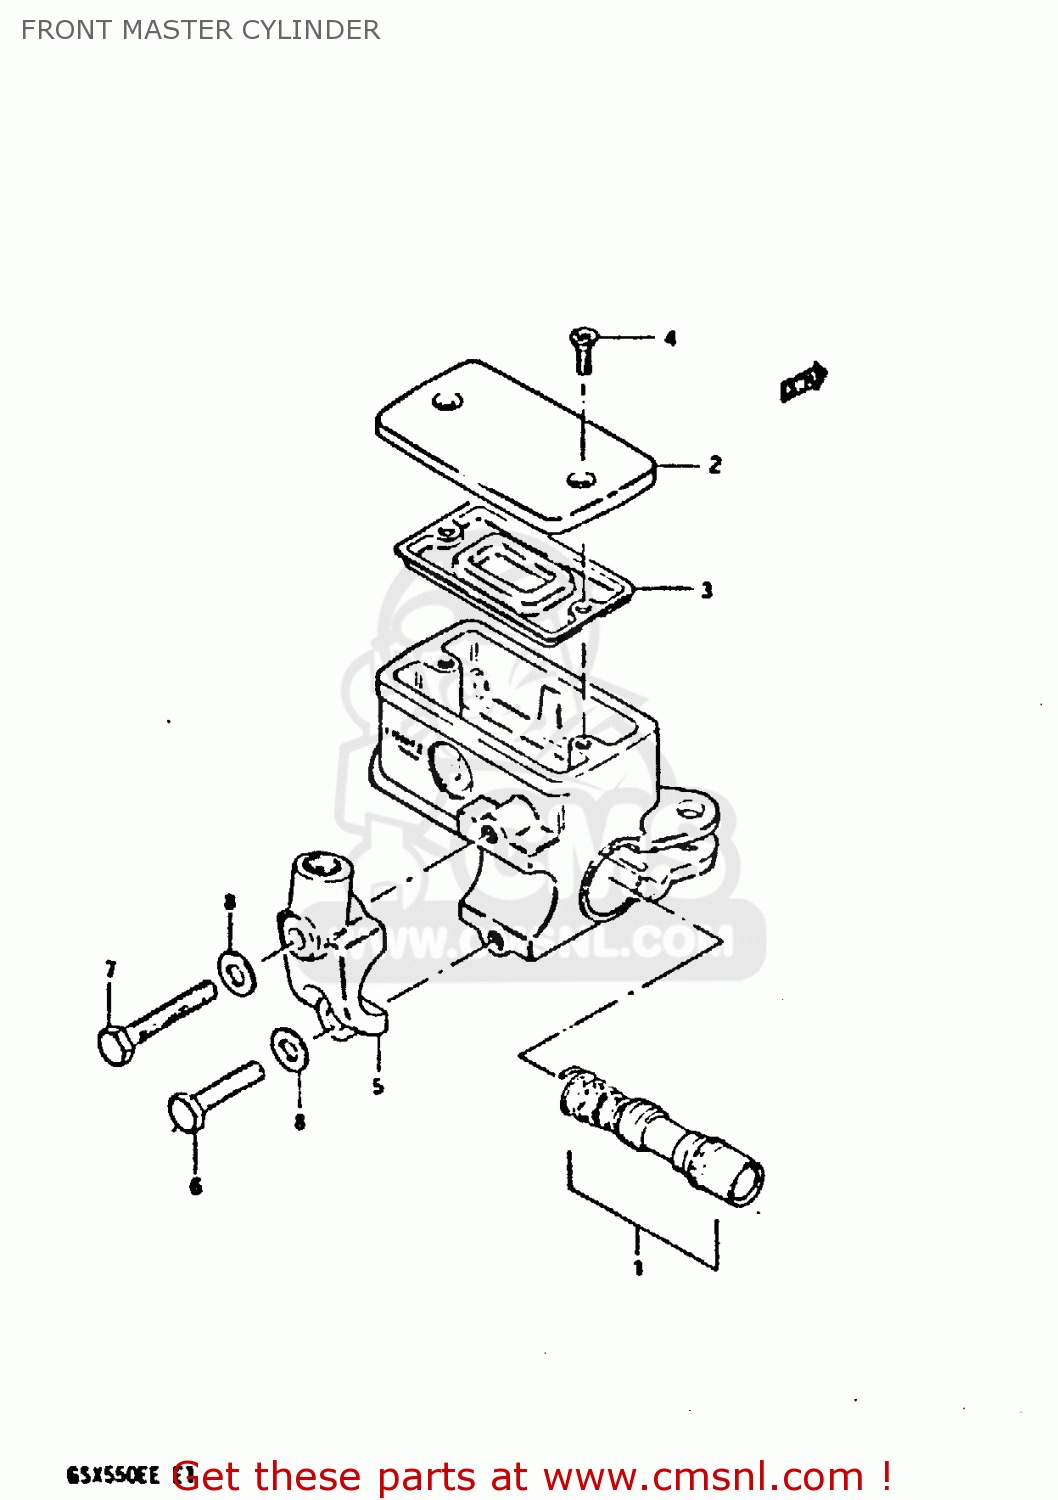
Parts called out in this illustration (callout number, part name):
1	PISTON & CUP SET
2	CAP
3	4
4	SCREW
5	HOLDER
6	BOLT
7	BOLT
8	WASHER
